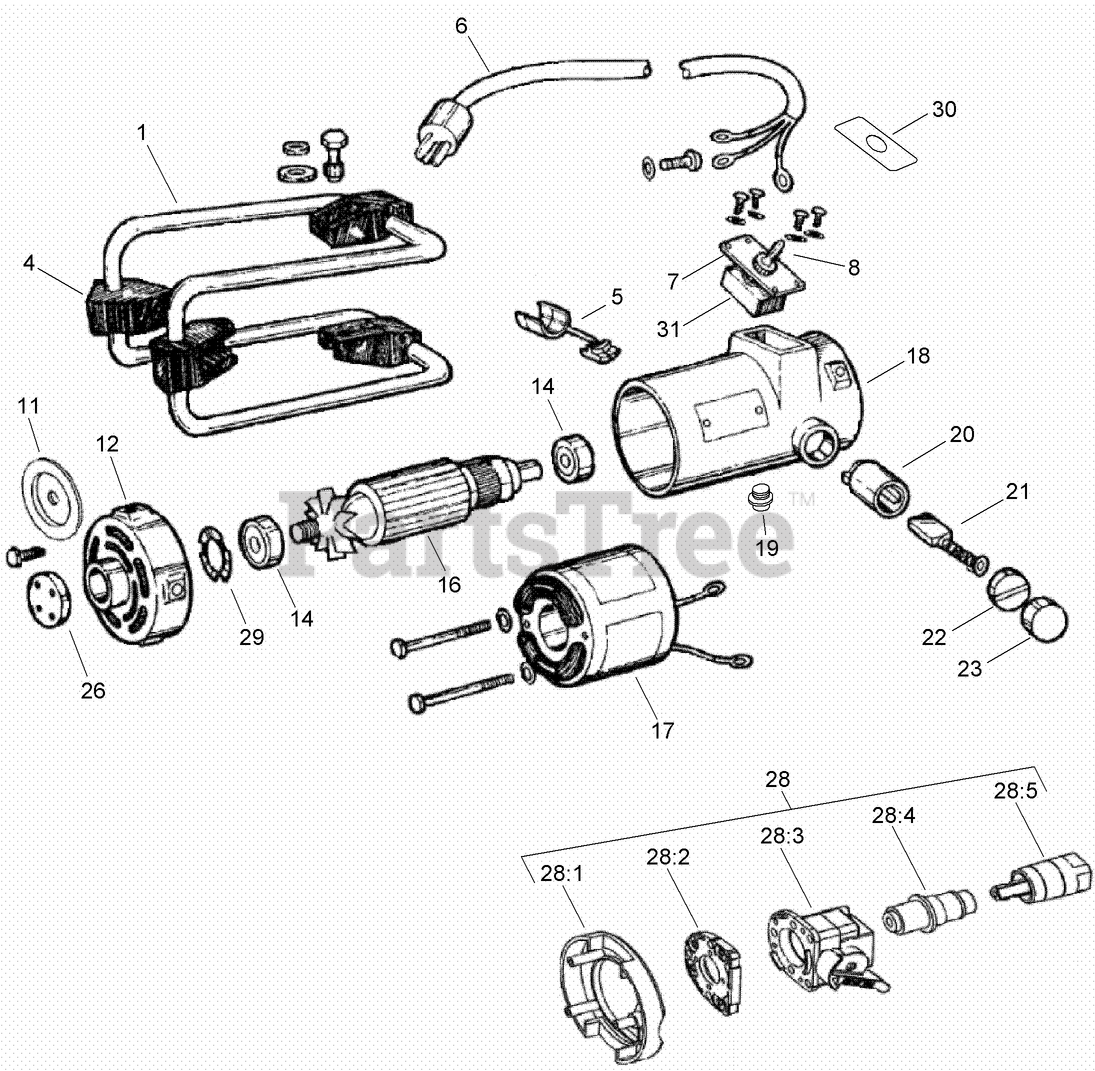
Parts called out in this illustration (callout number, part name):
1	FRAME ASM
4	MOUNT-SHOCK
5	STRAIN RELIEF ASM
6	CORD ASM
7	SWITCH PLATE ASM
8	BOOT-RUBBER, SWITCH
11	BAFFLE ASM
12	BELL-END
14	BEARING
16	ARMATURE (115V)
17	FIELD (115V)
18	HOUSING
19	PLUG-PORT, ACCESS
20	HOLDER-BRUSH
22	SCREW-CAP
23	CAP-THREADED, PROTECTIVE
28	QUICK DISCONNECT KIT
28:1	BAFFLE-RH
28:2	SPACER
28:3	CASING-ADAPTOR
28:4	CORE ADAPTOR ASM
28:5	COUPLER-SHAFT
29	RING-TOLERANCE
30	DECAL-SWITCH PLATE
31	KILL SWITCH ASM
